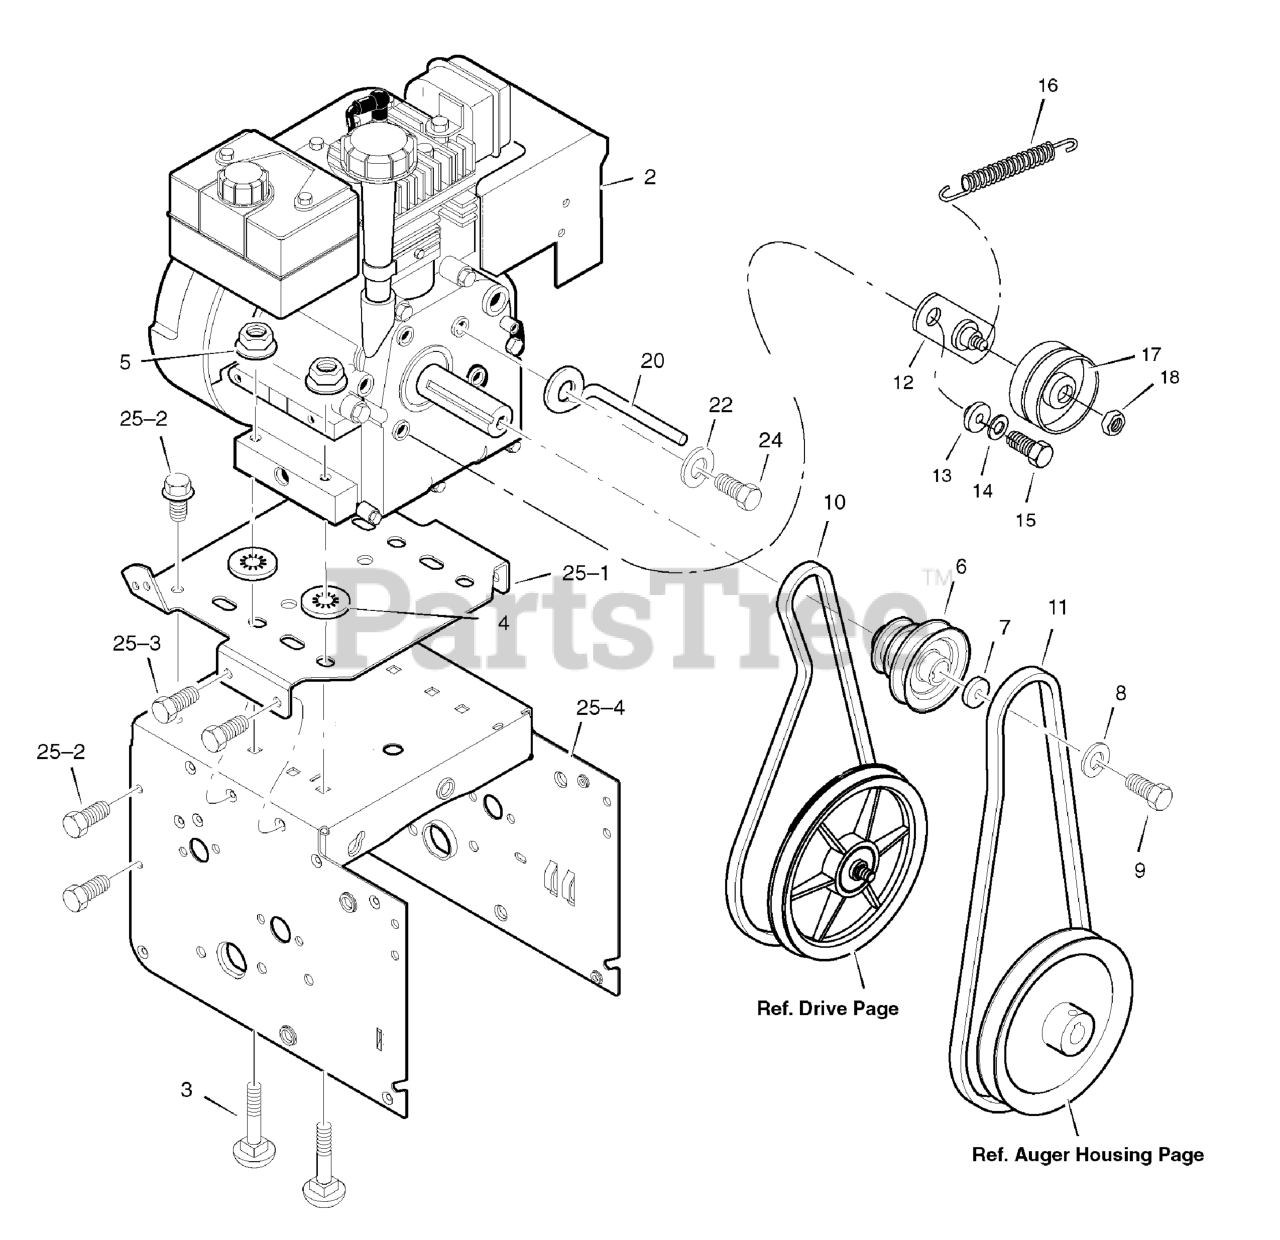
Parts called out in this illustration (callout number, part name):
2	Engine *
3	BOLT, CARRIAGE 5/16-18
4	RETAINER, PUSH
5	NUT 5/16-18
6	PULLEY, ENGINE
7	WASHER
8	WASHER .38ID
9	SCREW, 3/8-24 x 1.00
10	BELT, DRIVE
11	BELT, AUGER
12	BRACKET ASSEMBLY, IDLER
13	BUSHING, IDLER BRACKET
14	WASHER, SPLIT
15	SCREW 5/16-24 X 0.75
16	SPRING, IDLER TRACTION DRIVE
17	PULLEY, IDLER
18	NUT, JAM 3/8-16
20	GUIDE, BELT
22	WASHER .31X.58X.08
24	SCREW, 5/16-24 x 0.75
25-1	PLATE, ENGINE MOUNT
25-2	SCREW, TAP 1/4-20 X .63
25-3	SCREW, TAP 5/16-18 X .50
25-4	FRAME, MOTOR BOX
